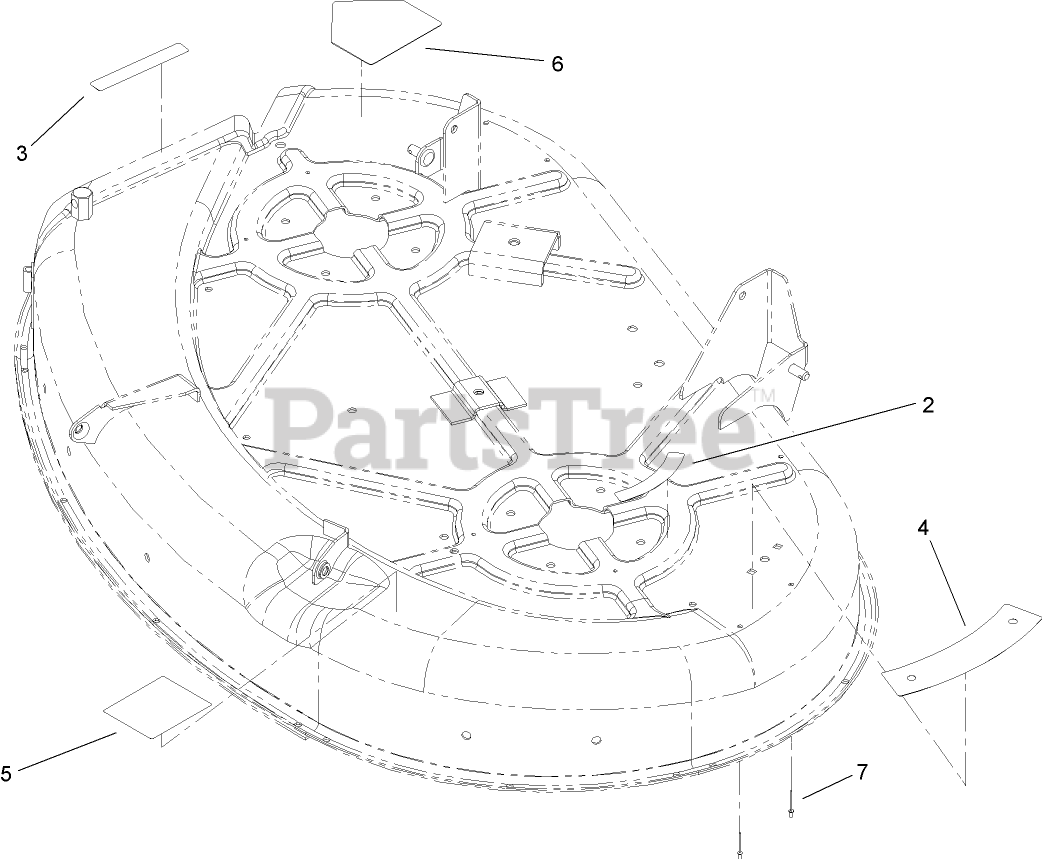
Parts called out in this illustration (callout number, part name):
2	DECAL-DANGER, SHIELD
3	DECAL-DANGER, DEFLECTOR
4	DECAL-DANGER
5	DECAL-ROUTING, BELT
6	DECAL-DANGER
7	RIVET-BLIND
